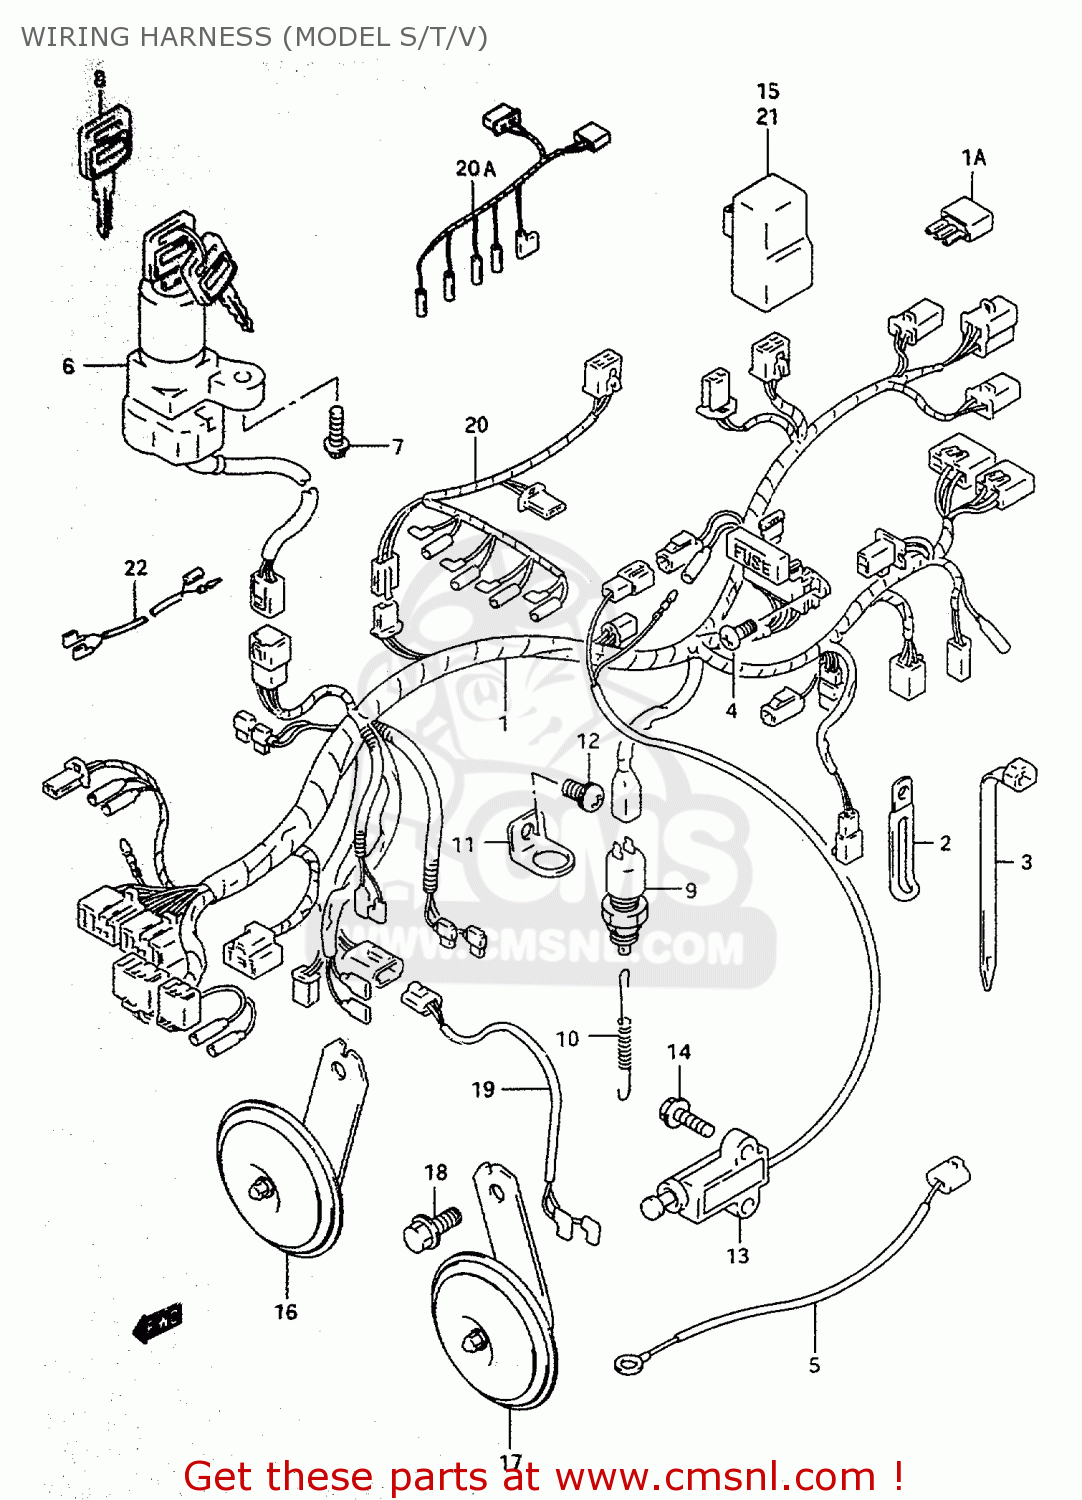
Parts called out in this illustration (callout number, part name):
1	HARNESS,WIRING
1A	DIODE(STANLEY DE8804)
2	CLAMP(L:45)
3	CLAMP(L:95)
4	SCREW 6X12
5	WIRE,OIL PRESSURE SWITCH LEAD
6	LOCK ASSY,STEERING
7	SCREW(6X18)
8	KEY,BLANK
9	SWITCH ASSY,STOP LAMP
10	SPRING
11	BRACKET,STOP LAMP SWITCH
12	SCREW
13	SWITCH ASSY,SIDE STAND
14	BOLT
15	RELAY ASSY
16	HORN ASSEMBLY,LOW PITCH
17	HORN ASSY,HIGH
18	BOLT
19	WIRE,HORN LEAD
20	WIRE,CARBURETOR HEATER LEAD
20A	WIRE,CARB HEATER LEAD
21	RELAY ASSY
22	WIRE,CLUTCH LEAD
